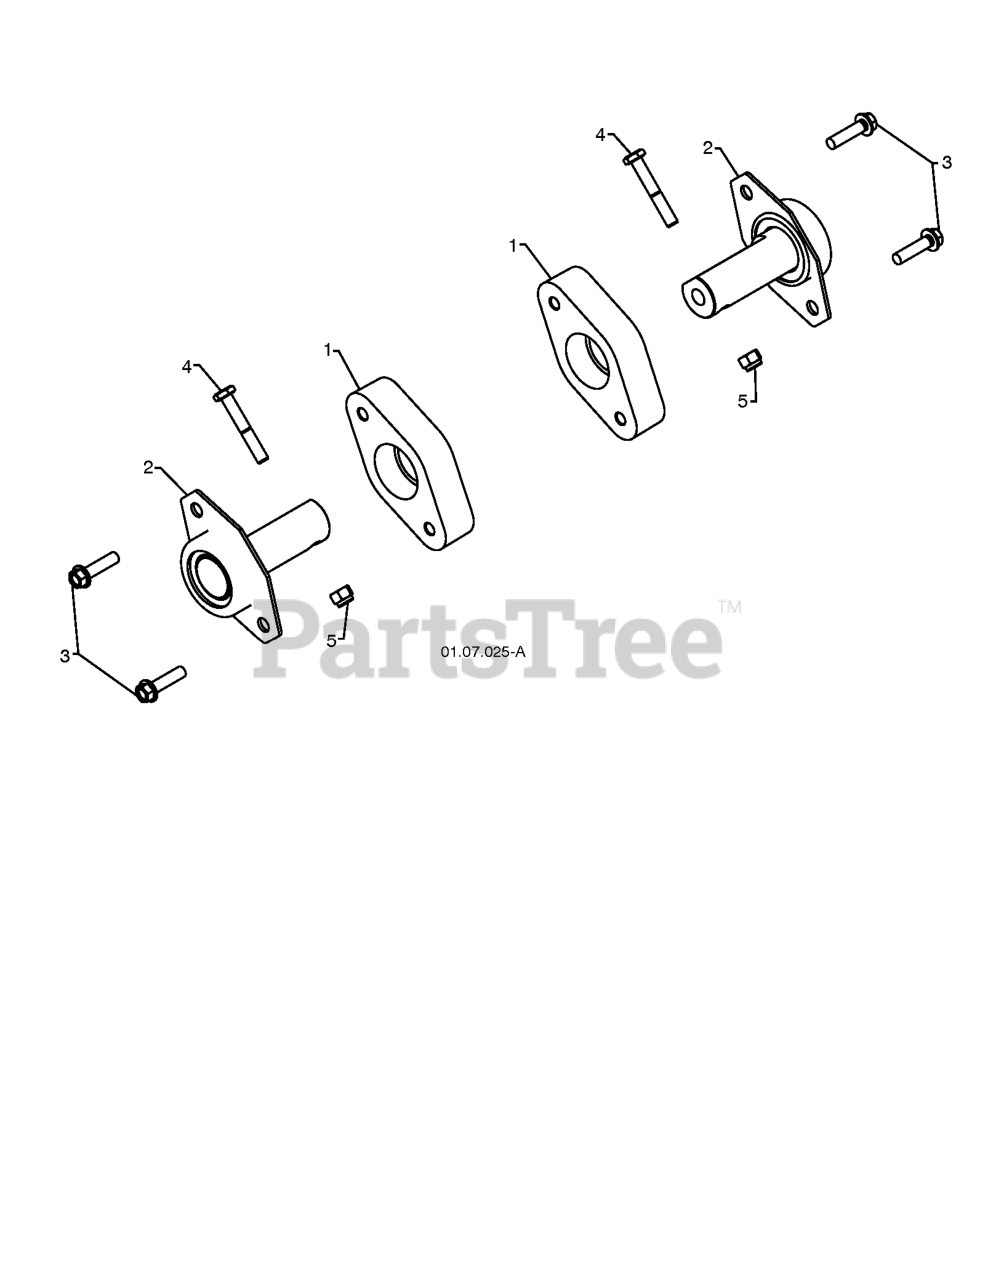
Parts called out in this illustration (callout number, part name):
1	RETAINER.PLASTIC
2	BEARING.BALL.AUGER.FLAT.
3	SCREW, HEX HD 5/16X1
4	SCREW.HEX.HD1/4-20X
5	LOCKNUT.NYLOC.1/4-20
